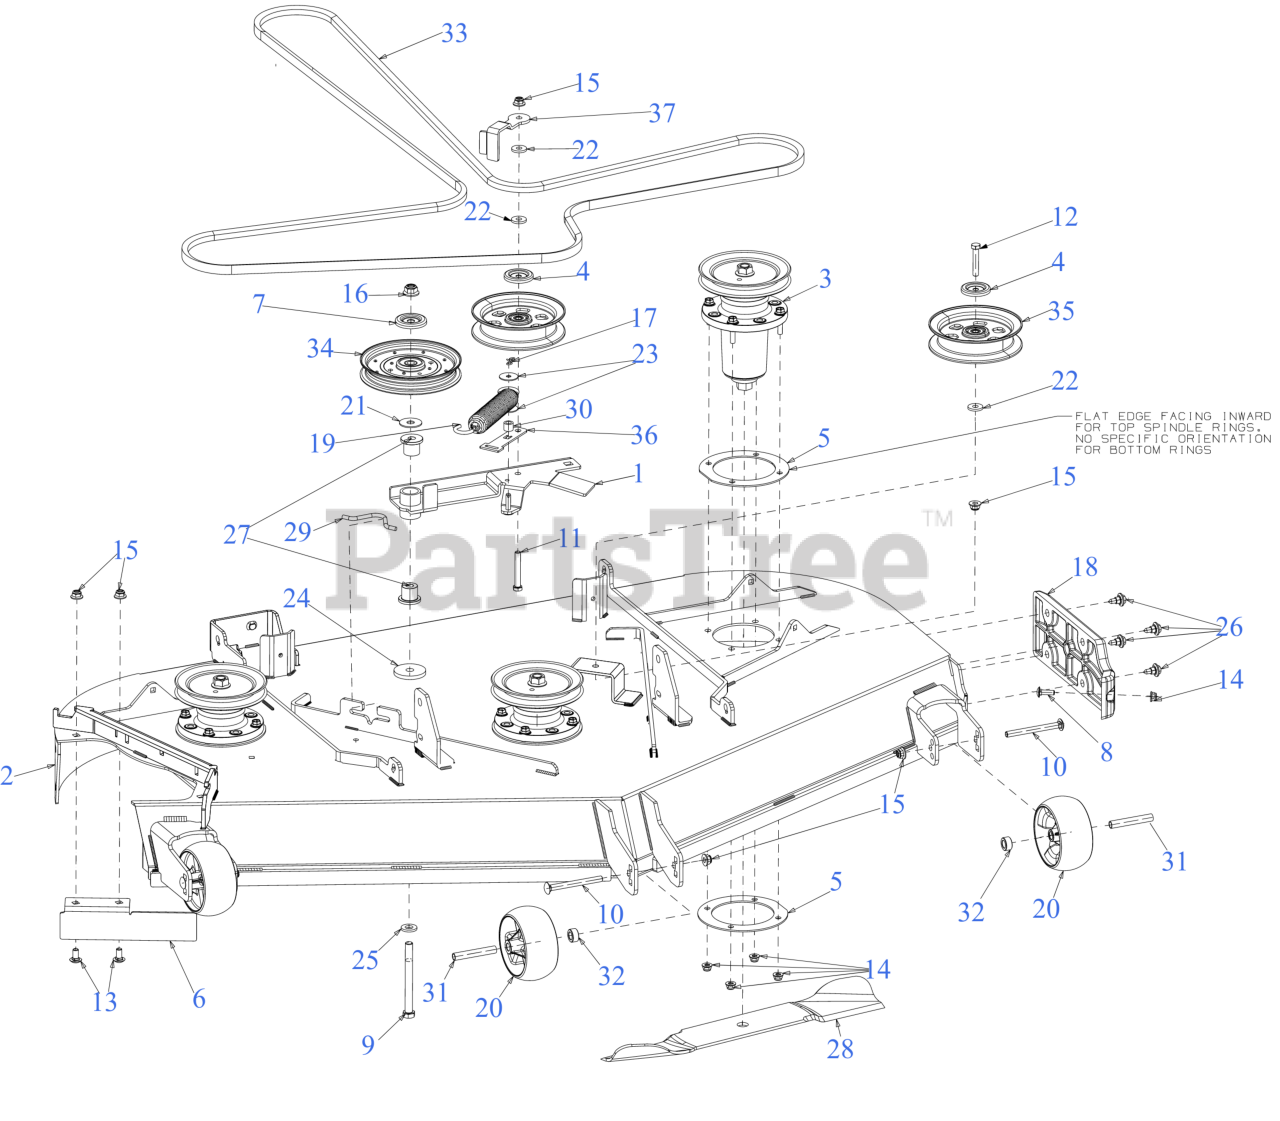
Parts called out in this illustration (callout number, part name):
1	54/60" DECK IDLER ASSEMBLY
2	60" FAB DECK SHELL
3	SPINDLE ASSEMBLY
3	Cub Cadet 60" SPINDLE ASSEMBLY (07386)
4	PULLEY CAP 1.875 DIA
5	SPINDLE PLATE
6	60" DECK CHUTE BAFFLE
7	PULLEY CAP (.540 x 2.041 DIA)
8	CARRIAGE BOLT 5/16-18 x 1.00
9	BOLT-HEX 1/2-13X5.0 GR5
10	CARRIAGE BOLT 3/8-16 x 4.00 GR5
11	HEX SCREW-3/8-16X2.5 GR5
12	SCREW 3/8-16 x 2.0 GR 8
13	CARRIAGE BOLT 3/8-16 x .75
14	FLANGE LOCK NUT 5/16-18
17	BOW TIE COTTER PIN 1/4-5/16
18	DECK SKID PLATE
19	SPRING 1.25" DIA x 8.5" LONG
20	DECK WHEEL
20	WHEELS-DELUXE 5"
21	WASHER .51 x 1.5 x .07
22	FLAT WASHER .385 x 1.00 x .135
23	FLAT WASHER .322 ID x 1.25 x .060
24	FLAT WASHER .53"x2.125"x.25"
25	FLAT WASHER .531X1.060X.134
26	SHOULDER SCREW .43X.29X5/16-18 TT
27	FLANGE BEARING
29	DECK SPRING HOOK
31	SPACER .38X.49X3.05LG
32	SPACER-.505 1D
33	V-BELT B SEC x 162.25
33	Cub Cadet DECK BELT
34	IDLER PULLEY 6.0" DIA
35	5" FLAT IDLER PULLEY
36	BELT KEEPER
37	54/60" IDLER KEEPER
